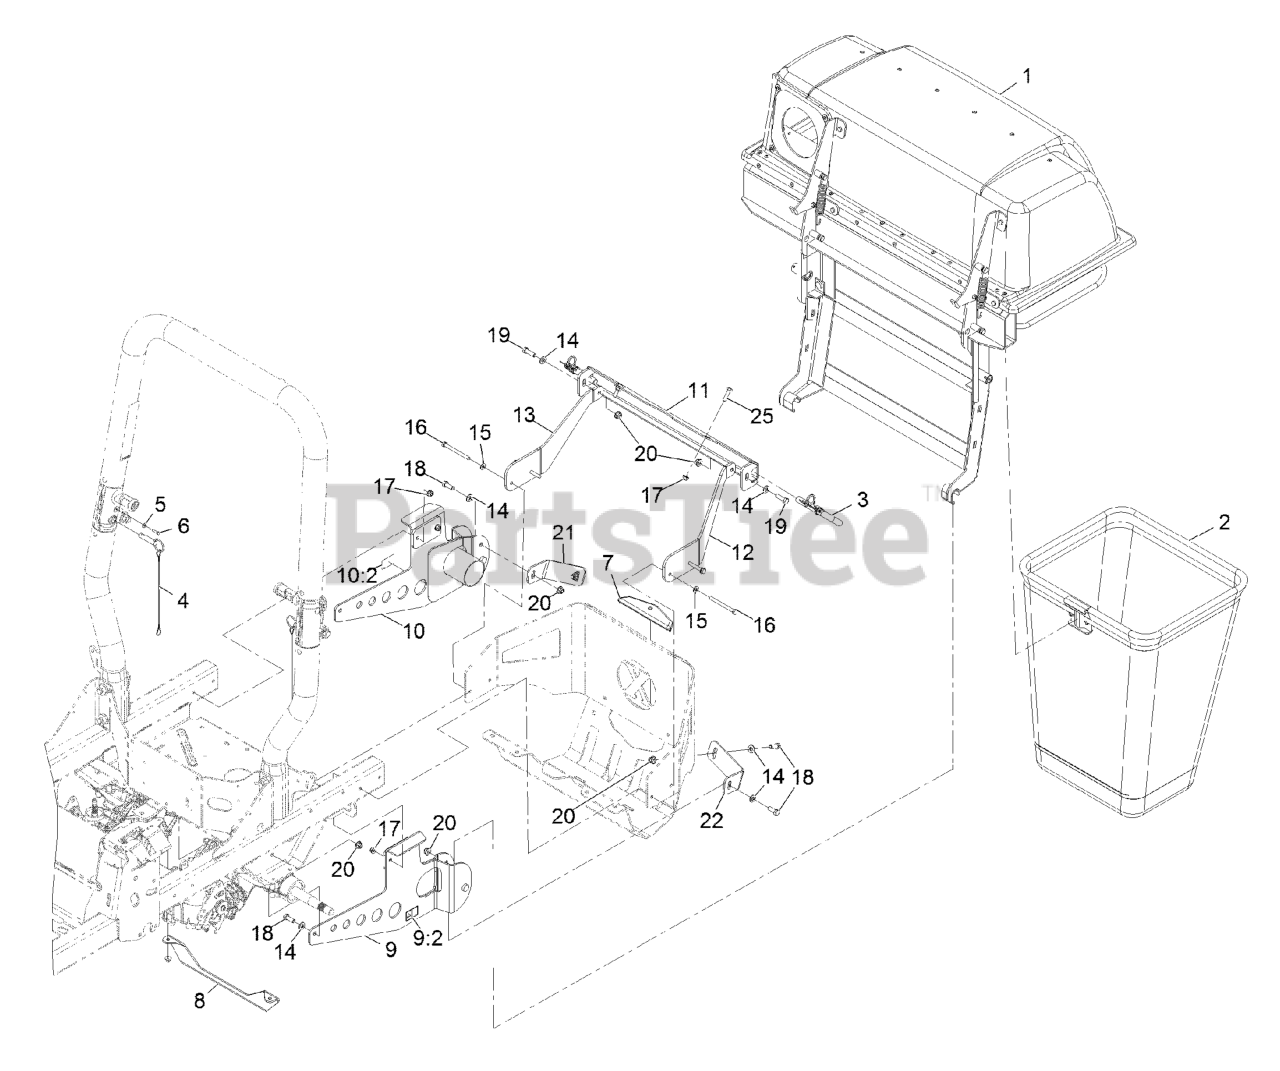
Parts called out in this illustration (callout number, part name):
1	Asm, Hood & Frame
2	BAG AND FRAME ASM
3	PIN-MOUNT, BAGGER
4	HITCH PIN ASM
5	WASHER-FLAT
7	COVER-HITCH
8	SUPPORT-TRANSMISSION
9	SUPPORT-BAGGER, LOWER LH
9:2	DECAL-WARNING
10	SUPPORT-BAGGER, LOWER RH
10:2	DECAL-WARNING
11	MOUNT-BAGGER LWR
12	BRACKET-UPPER, LH
13	BRACKET-UPPER, RH
14	WASHER-FLAT
15	WASHER-PLAIN
17	NUT-HF, NI
18	SCREW-HH
19	SCREW-HH
20	NUT-HF, NI
21	BRACKET-BAGGER, RH
22	BRACKET-BAGGER, LH
25	SCREW-HH
